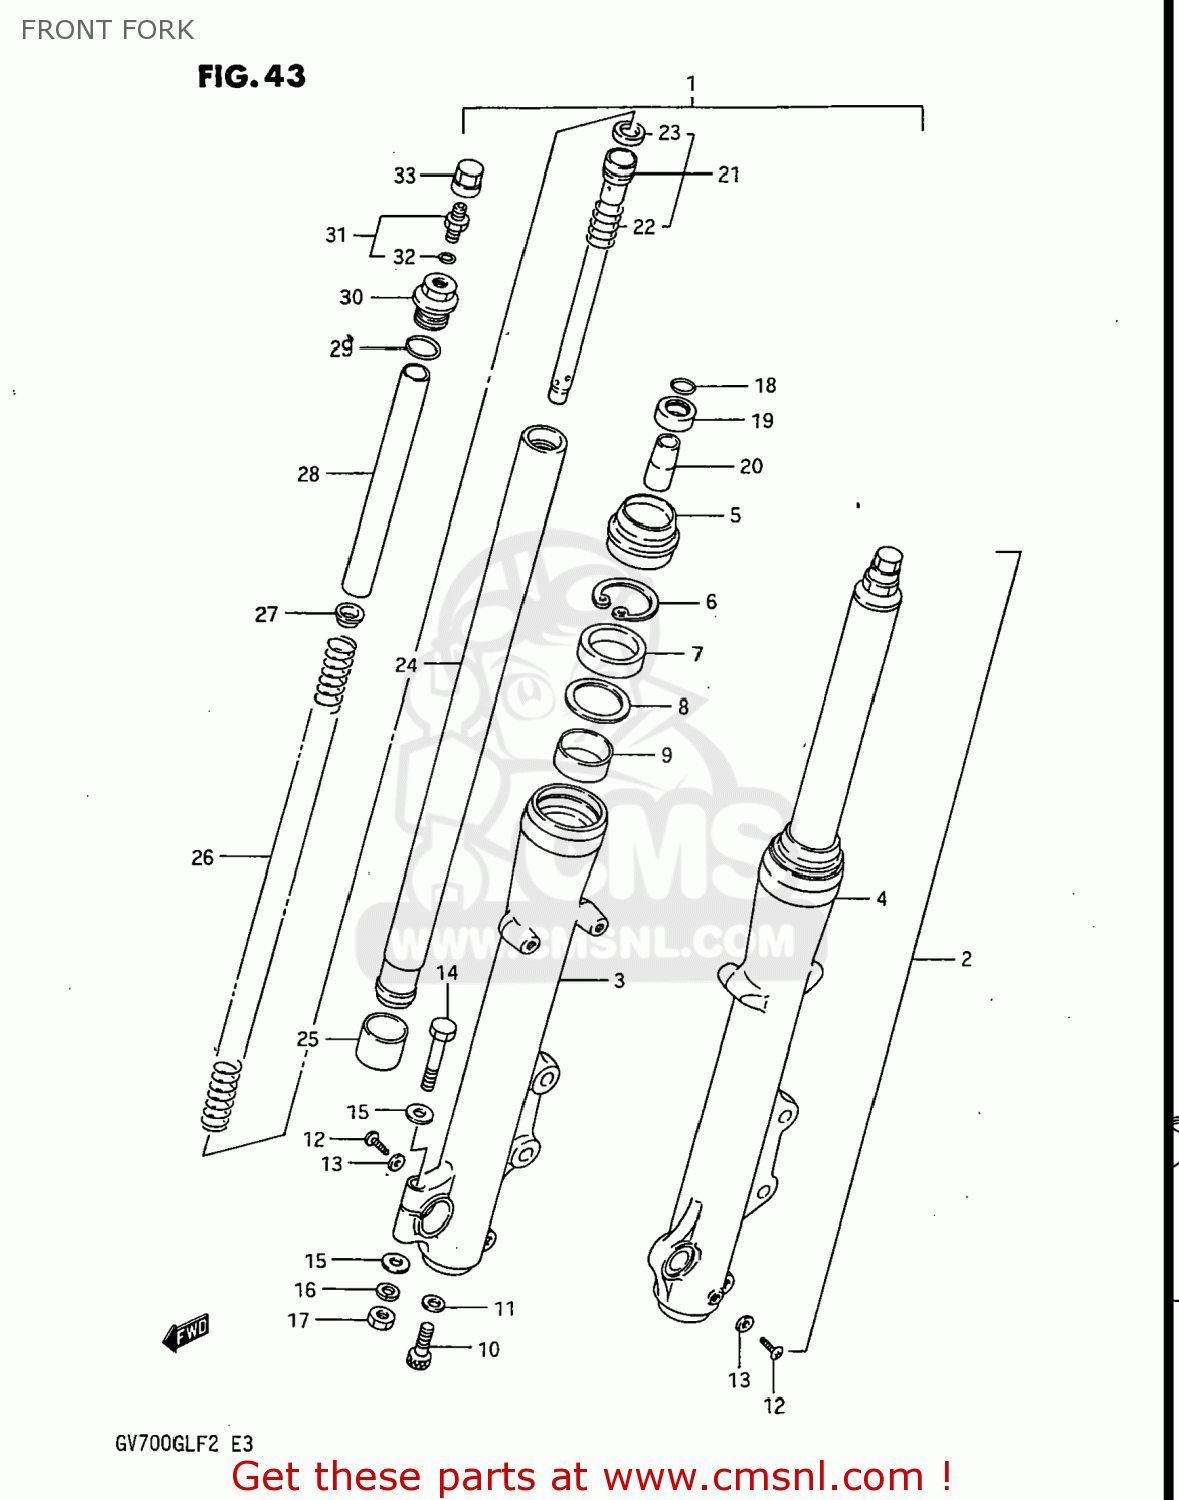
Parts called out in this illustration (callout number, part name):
1	DAMPER ASSEMBLY,FRONT FORK
2	DAMPER ASSEMBLY,LEFT
3	TUBE,OUTER,RIGHT
4	TUBE,OUTER,LEFT
5	SEAL,DUST
6	RING,OIL SEAL STOPPER
7	SEAL,OIL
8	WASHER,FORK OIL SEAL
9	METAL,FR FORK SLIDE
10	BOLT,CYLINDER
11	GASKET,CYLINDER (NAS)
12	SCREW
13	GASKET,DRAIN,PLUG (NAS)
14	BOLT 8X50
15	WASHER
16	WASHER,LOCK,8.
17	NUT
18	RING,SNAP
20	PIECE,OIL LOCK
21	CYLINDER,FRONT FORK
22	SPRING,REBOUND
23	RING,PISTON
24	TUBE,FORK,INNER
25	METAL,SLIDE FR FORK
26	SPRING,FRONT FORK
27	GUIDE
28	SPACER,FRONT FORK SPRING
29	O RING
30	CAP,FORK INNER TUBE
31	VALVE,FRONT FORK AIR
32	O-RING
33	CAP,FRONT FORK AIR VALVE
